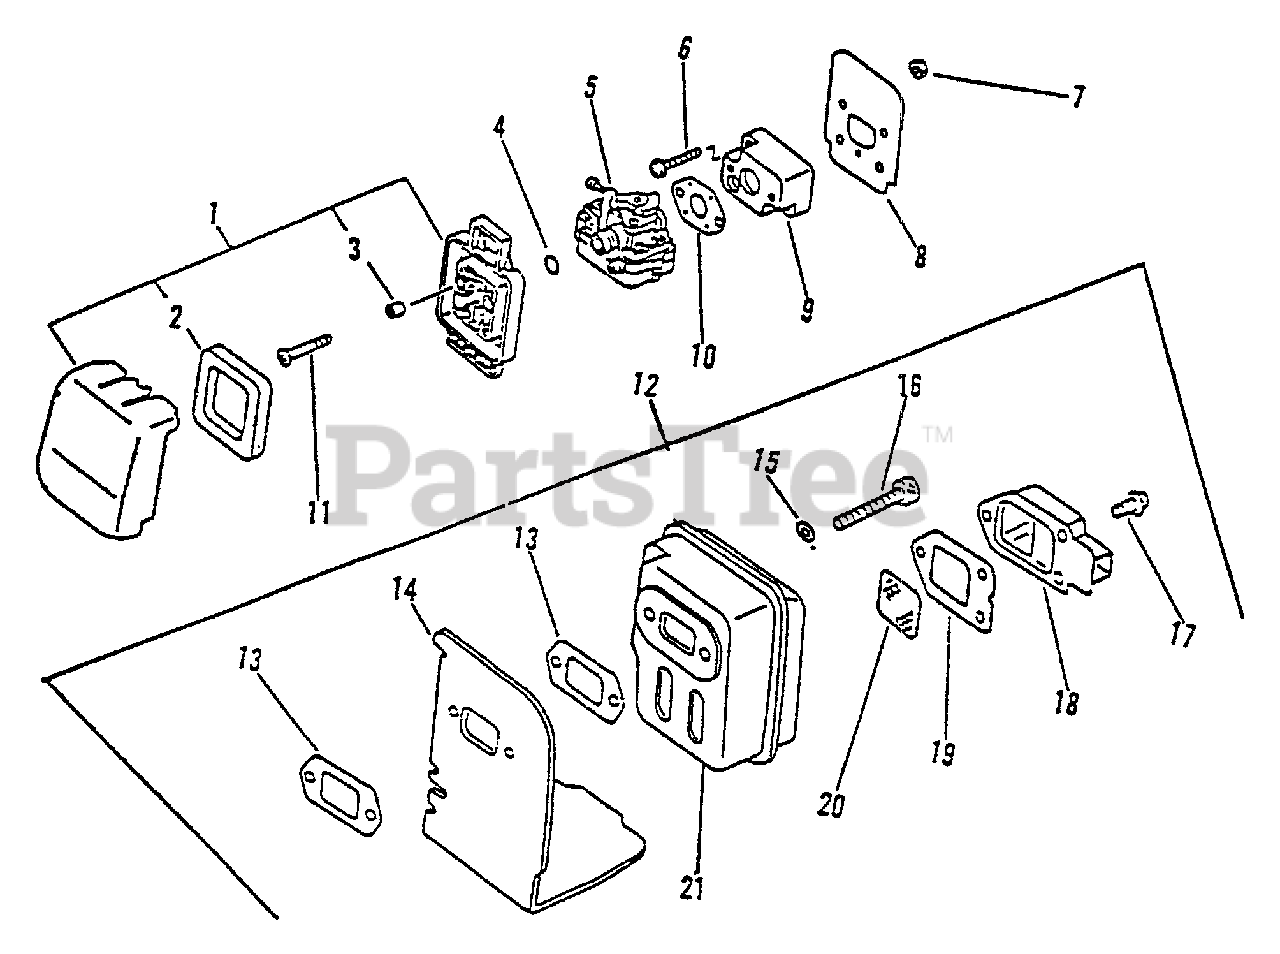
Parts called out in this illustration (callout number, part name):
1	FILTER ASSY, AIR
2	FILTER, AIR
3	SLEEVE
4	O-RING 15
5	CARBURETOR - WLY-10
6	SCREW 5×22
7	NUT M5
8	HEAT SHIELD, INTAKE
9	INSULATOR, INTAKE
10	GASKET, INTAKE
11	SCREW 5×64
12	MUFFLER ASSY
13	GASKET, EXHAUST
14	COVER, EXHAUST
15	WASHER, FLAT 5.5×10×0.8
16	BOLT 5×55
17	SCREW 4×10
18	GUIDE, EXHAUST - INNER
19	GASKET, EXHAUST
20	SCREEN, SPARK ARRESTER
